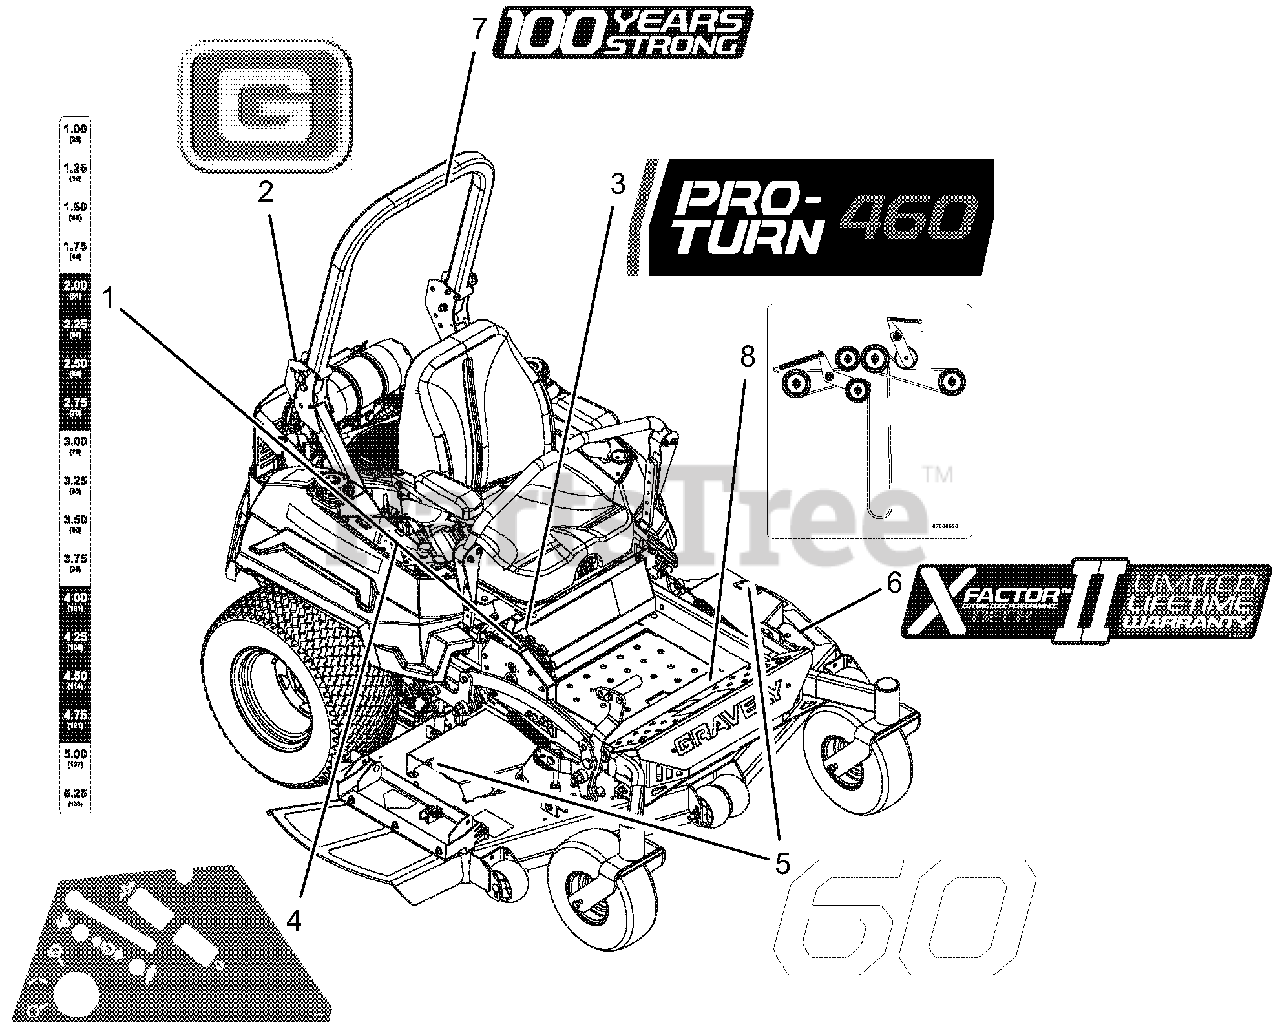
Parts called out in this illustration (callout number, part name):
1	DECAL, PT400 HEIGHT OF CUT
2	DECAL, GRAVELY BRAND
3	DECAL, PRO-TURN 460
4	DECAL, EFI CONTROL PANEL
5	DECAL, 60"
6	DECAL, X-FACTOR DECK
7	DECAL, GRAVELY 100 YR
8	DCL,BELT ROUTE-RH BK-SIDE IDLR
